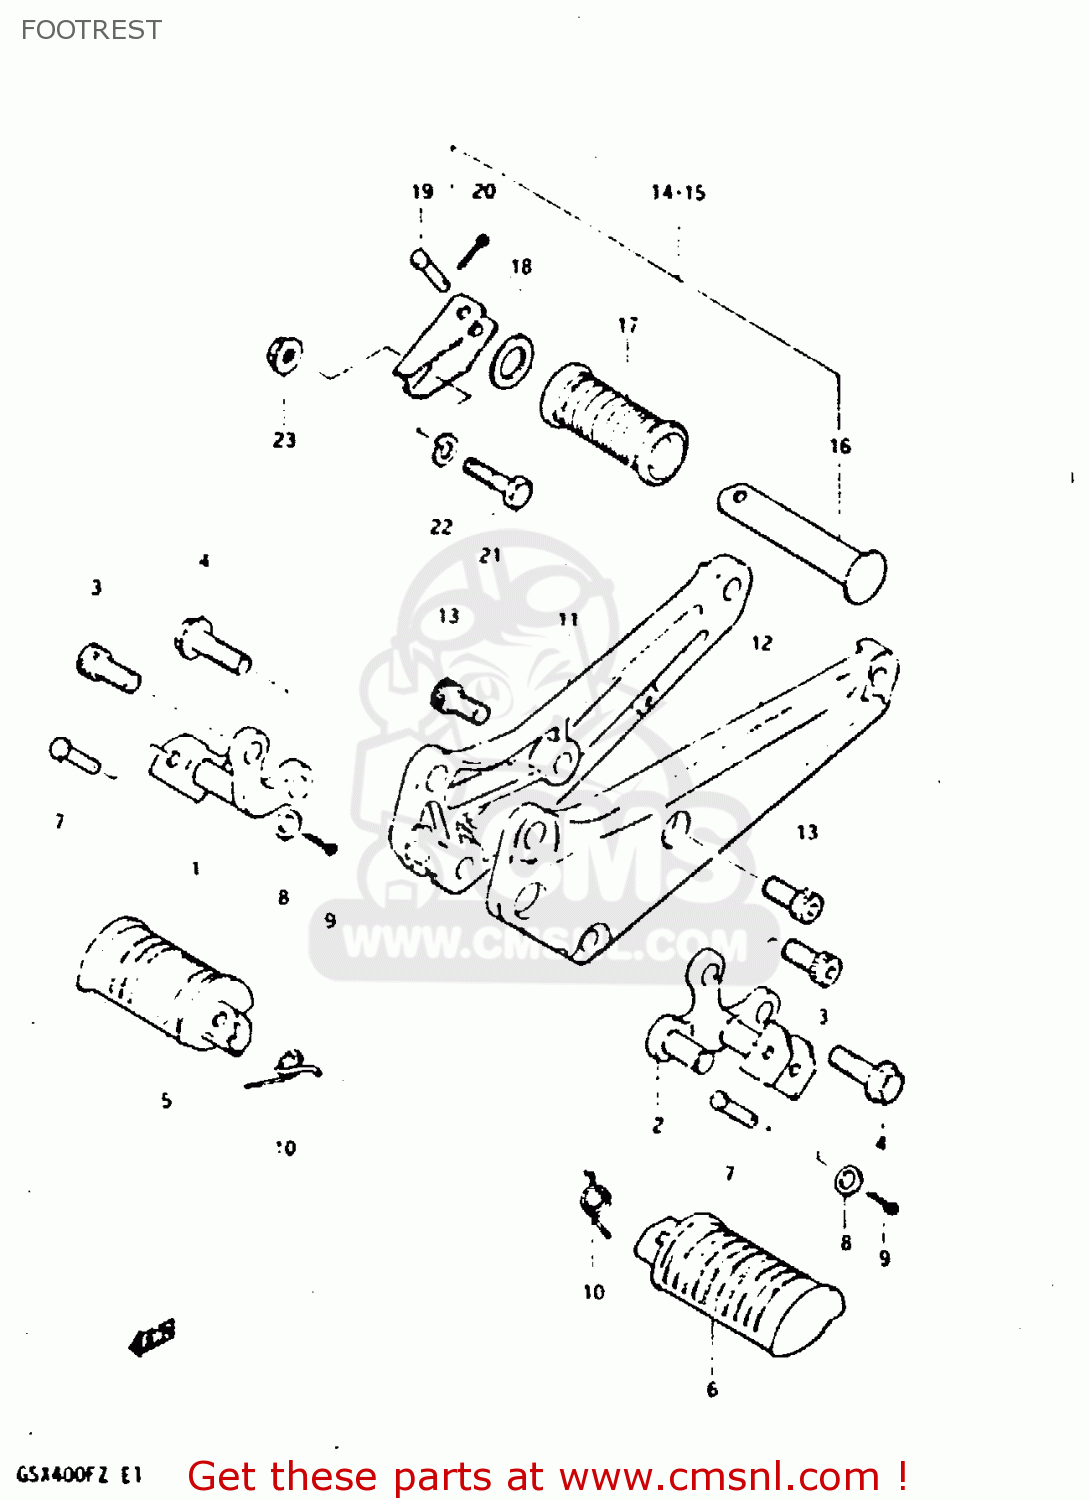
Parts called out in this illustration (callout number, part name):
1	BAR, FRONT FOOTREST RH
2	BAR, FRONT FOOTREST LH
3	BOLT
4	BOLT, LOWER
5	RUBBER,FR FOOT
6	RUBBER, LH
7	PIN
8	WASHER
9	PIN 20X20
10	SPRING
11	BRACKET, MUFFLER RH
12	BRACKET, MUFFLER LH
13	BOLT
14	FOOTREST, PILLION RH
15	FOOTREST, PILLION LH
16	BAR,FOOTREST RUBBER
17	RUBBER,PILLION FOOTREST
18	WASHER (19.5X32X2)
19	PIN
20	PIN 20X20
21	BOLT,M10X1.25X
22	LOCK WASHER
23	NUT
